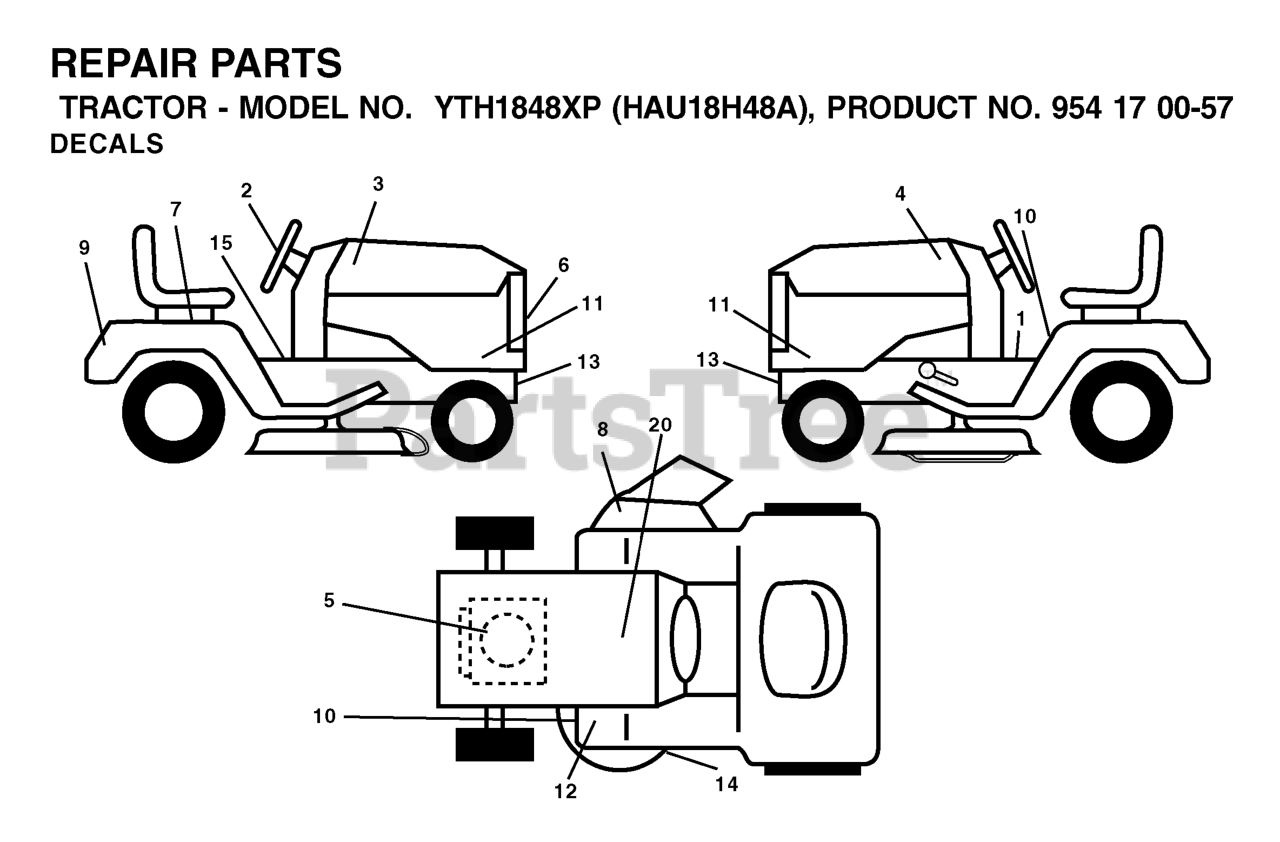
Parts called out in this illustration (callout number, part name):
1	DECAL READ OWNER'S MAN SYMS
2	DECAL.WHEEL.STEERING.HUSQ.PERM
3	HOOD DECAL
4	HOOD DECAL
5	DECAL ENGINE
6	DECAL.GRILLE.HUSQ
7	DECAL
8	DECAL MOWER CUT/FINGER
9	DECAL, FENDER
10	DECAL CLUTCH/BRAKE
11	DECAL HOOD
12	DECAL
14	DECAL V-BELT SCHEMATIC
15	DECAL PARK BRAKE
20	DECAL BTRY SYMBOLS
